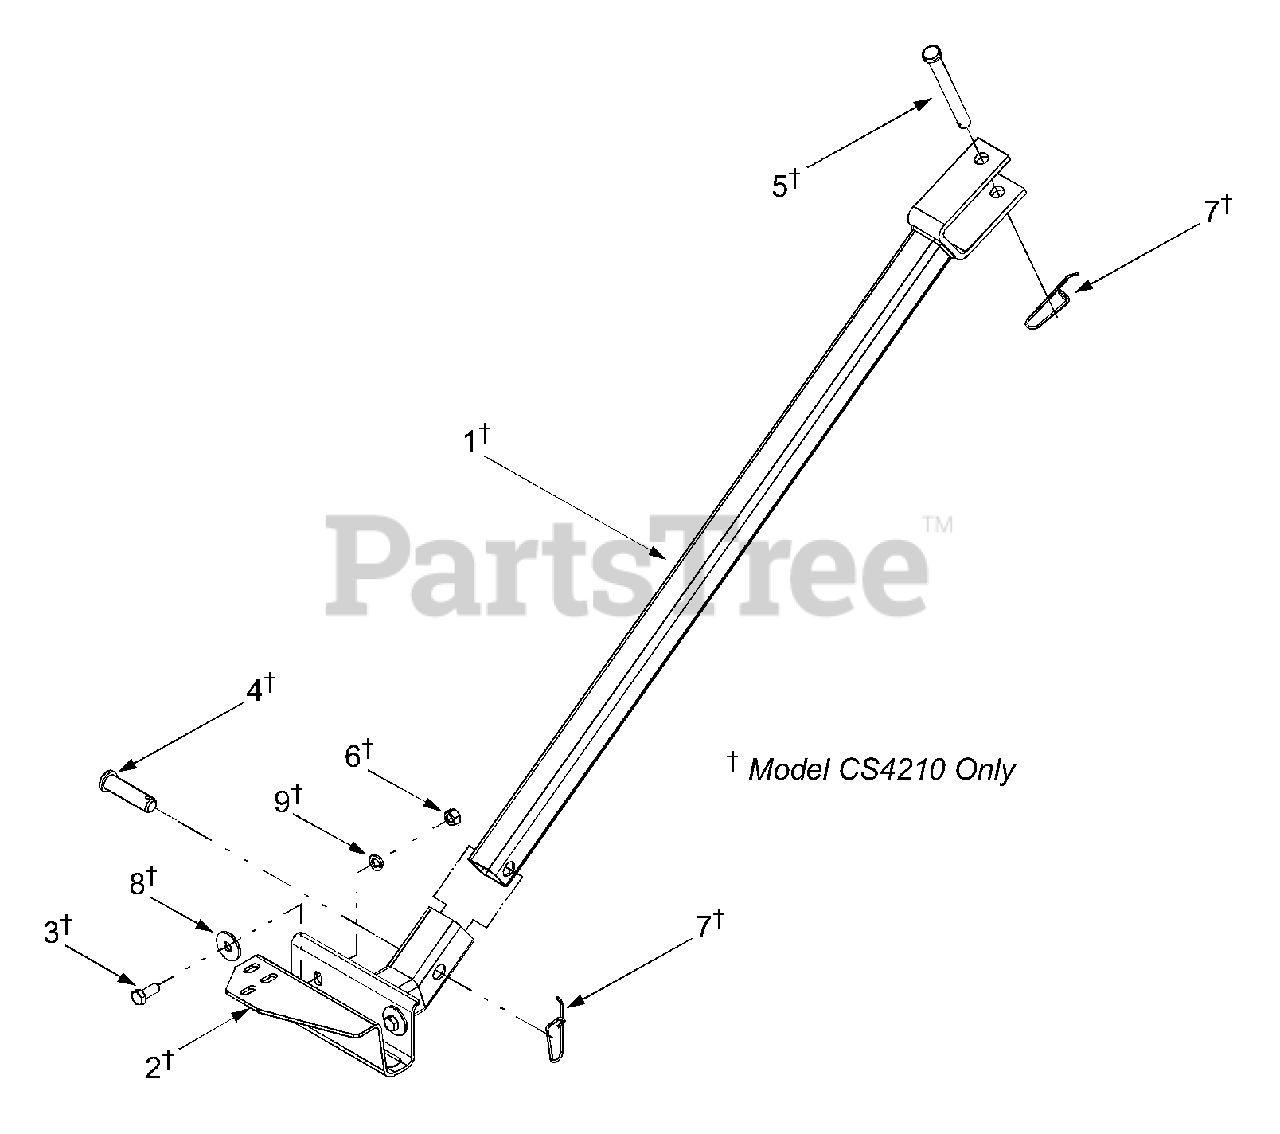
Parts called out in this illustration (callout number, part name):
3	Hex Cap Screw, 3/8-16 x.88
4	Clevis Pin,.625 x 2.4
5	Clevis Pin,.50 x 4.62
6	Hex Nut, 3/8
7	Spring Pin
8	Flat Washer,.411 x 1.25 x 1.0
9	Lock Washer, 3/8
